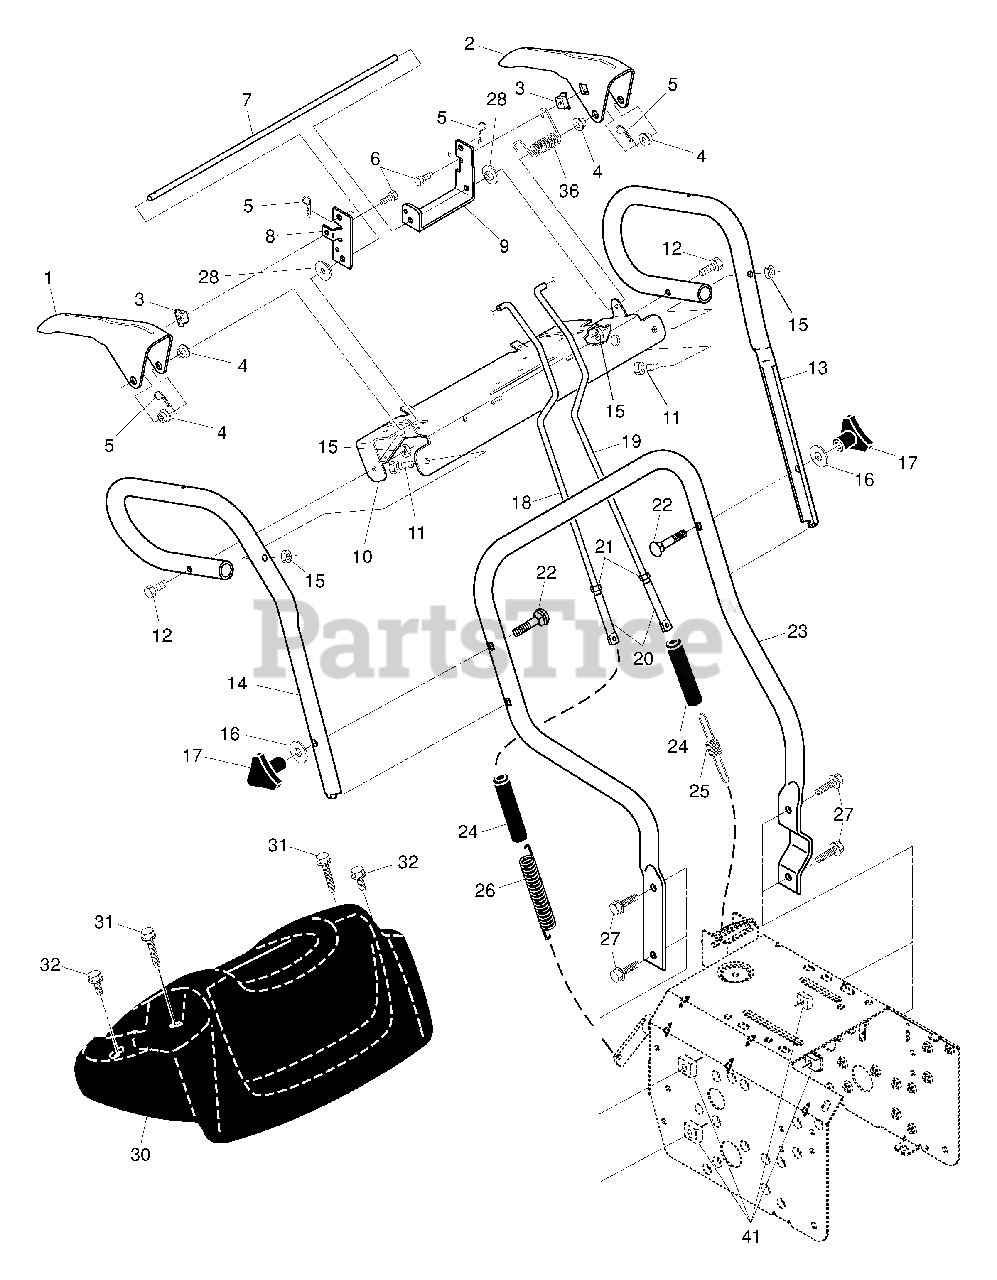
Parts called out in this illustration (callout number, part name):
1	Lever, Auger Control, RH
2	Lever, Traction Drive Control, LH
3	Nut, Cage 1/4-20
4	Bushing, Flange
5	Retainer, Hairpin
6	Screw, Hex Head 1/4-20 x 3/4
7	Rod, Interlock
8	Arm, Impeller Rod
9	Arm, Traction Rod
10	Panel, Control
11	Screw, Hex Head 5/16-18 x 1-1/2
12	Screw, Hex Head 5/16-18 x 1-3/4
13	Handle Tube, LH
14	Handle Tube, RH
15	Nut, Lock 5/16-18
16	Washer, Flat 3/8
17	Knob, Handle
18	Rod, Auger Control
19	Rod, Traction Control
20	End, Control Rod
21	Nut, Hex, Jam 5/16-18
22	Bolt, Carriage 3/8-16 x 2-1/4
23	Handle Tube, Lower
24	Sleeve, Spring
25	Spring, Traction Drive
26	Spring, Auger Control
27	Screw, Hex Head 3/8-16 x 1
30	Console, Panel
31	Screw, Hex Head, Tapping #10-24 x 1-1/4
32	Screw, Hex Head, Tapping #10-24 x 1/2
